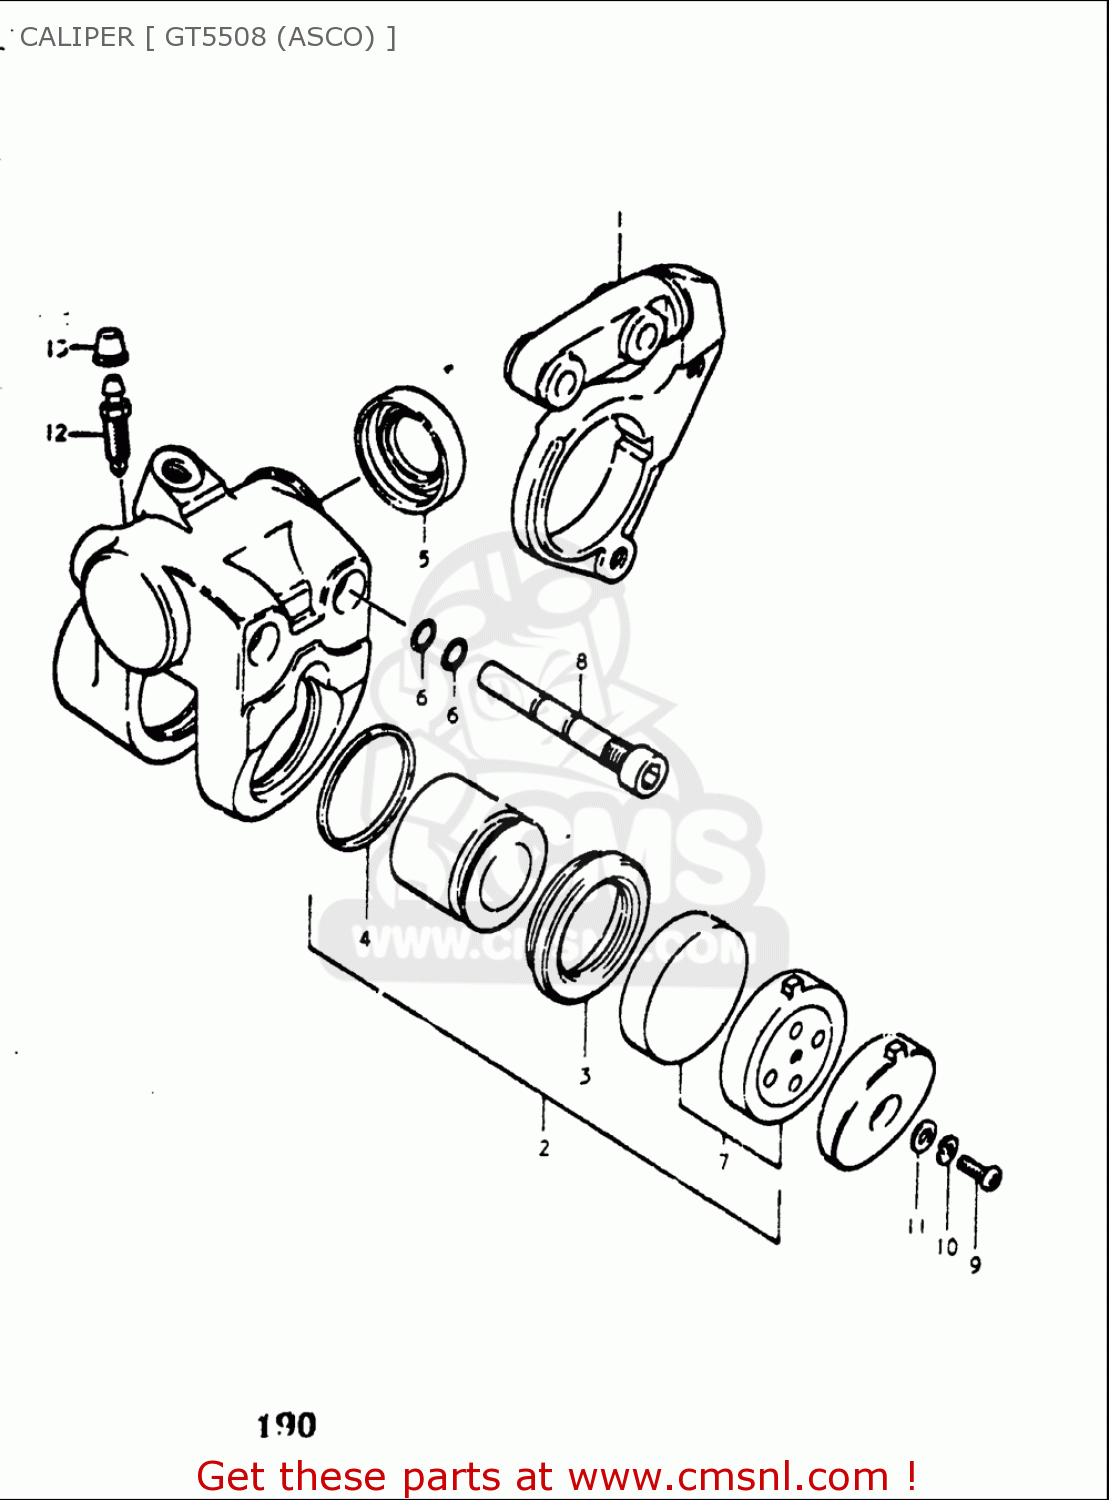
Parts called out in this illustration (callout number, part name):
1	HOLDER,CALIPER
3	BOOT,PISTON
4	SEAL,PISTON
5	BOOT,HOLDER
6	O RING,AXLE CALIPER
8	AXLE,CALIPER
9	SCREW
10	WASHER,LOCK
11	WASHER
12	BLEEDER
13	CAP,BLEEDER PLUG
